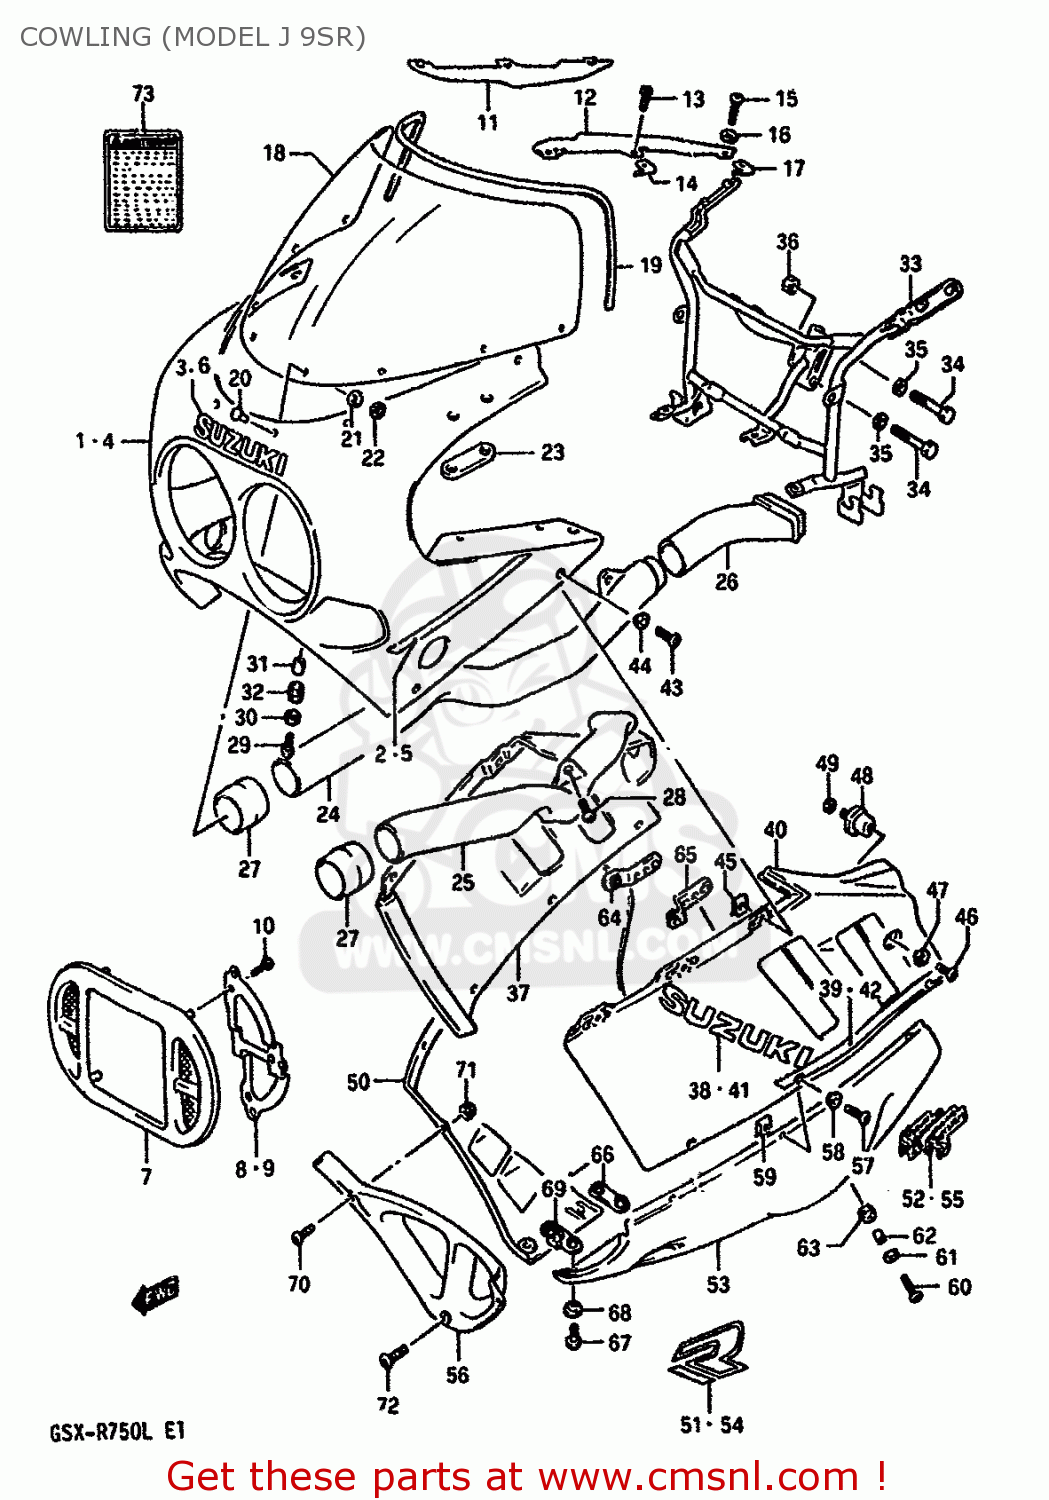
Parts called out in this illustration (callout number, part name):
1	BODY ASSEMBLY,COWLING
2	TAPE SET,COWLING
3	EMBLEM,COWLING,UPPER (W)
4	BODY ASSY,COWLING (BLUE/WHITE)
5	TAPE SET,COWLING
6	EMBLEM,COWLING,UPPER (W)
7	COVER,FRONT (WHITE)
8	PLATE,COVER RH
9	PLATE,COVER LH
10	TAPPING SCREW 4X10/A
11	PANEL,COWLING UPPER,RIGHT
12	COVER,COWLING,LEFT
13	SCREW(5X10)
14	NUT
15	SCREW(5X14)
16	WASHER(5.2X11X1)
17	NUT
18	WINDSCREEN
19	MOLDING
20	PIN,WINDSCREEN
21	CUSHION
22	NUT
23	CUSHION,RR VIEW MIRRORR
24	PIPE,AIR INTAKE,FRONT
25	PIPE,AIR INTAKE,FRONT
26	PIPE,AIR INTAKE RR,R
27	JOINT,AIR INTAKE
28	SCREW
29	SCREW(6X20)
30	WASHER(6.5X18X1)
31	SPACER
32	CUSHION
33	BRACE,COWLING
34	BOLT
35	WASHER,LOCK,8.
36	NUT ,8MM
37	COVER,COWLING SIDE,RIGHT
38	EMBLEM
39	TAPE,COWLING SIDE STRIPE
40	COVER,COWLING SIDE,LEFT
41	EMBLEM
42	TAPE,COWLING SIDE STRIPE
43	SCREW(5X18)
44	WASHER(5.2X14X1.5)
45	NUT,HEADLAMP HOUSING,UPPER
46	SCREW(6X12)
47	WASHER(6.3X16X1.5)
48	CUSHION,COWLING
49	WASHER,LOCK
50	COWLING,UNDER
51	EMBLEM,COWLING UNDER
52	EMBLEM,COWLING,UNDER
53	COWLING,UNDER LH (BLUE/WHITE)
54	EMBLEM,COWLING UNDER
55	EMBLEM,COWLING,UNDER
56	COWLING,UNDER,CENTER
57	SCREW(5X18)
58	WASHER(5.2X14X1.5)
59	NUT,HEADLAMP HOUSING,UPPER
60	SCREW(6X20)
61	WASHER(6.5X18X1)
62	SPACER
63	CUSHION
64	BRACKET
65	BRACE,COWLING UNDER,LH
66	BRACE,COWLING LWR COVER RR
67	SCREW(6X16)
68	WASHER(6.3X16X1.5)
69	BRACE,COWLING LWR COVER
70	SCREW(5X14)
71	NUT
72	SCREW(6X16)
73	LABEL (WARNING SCREEN)
